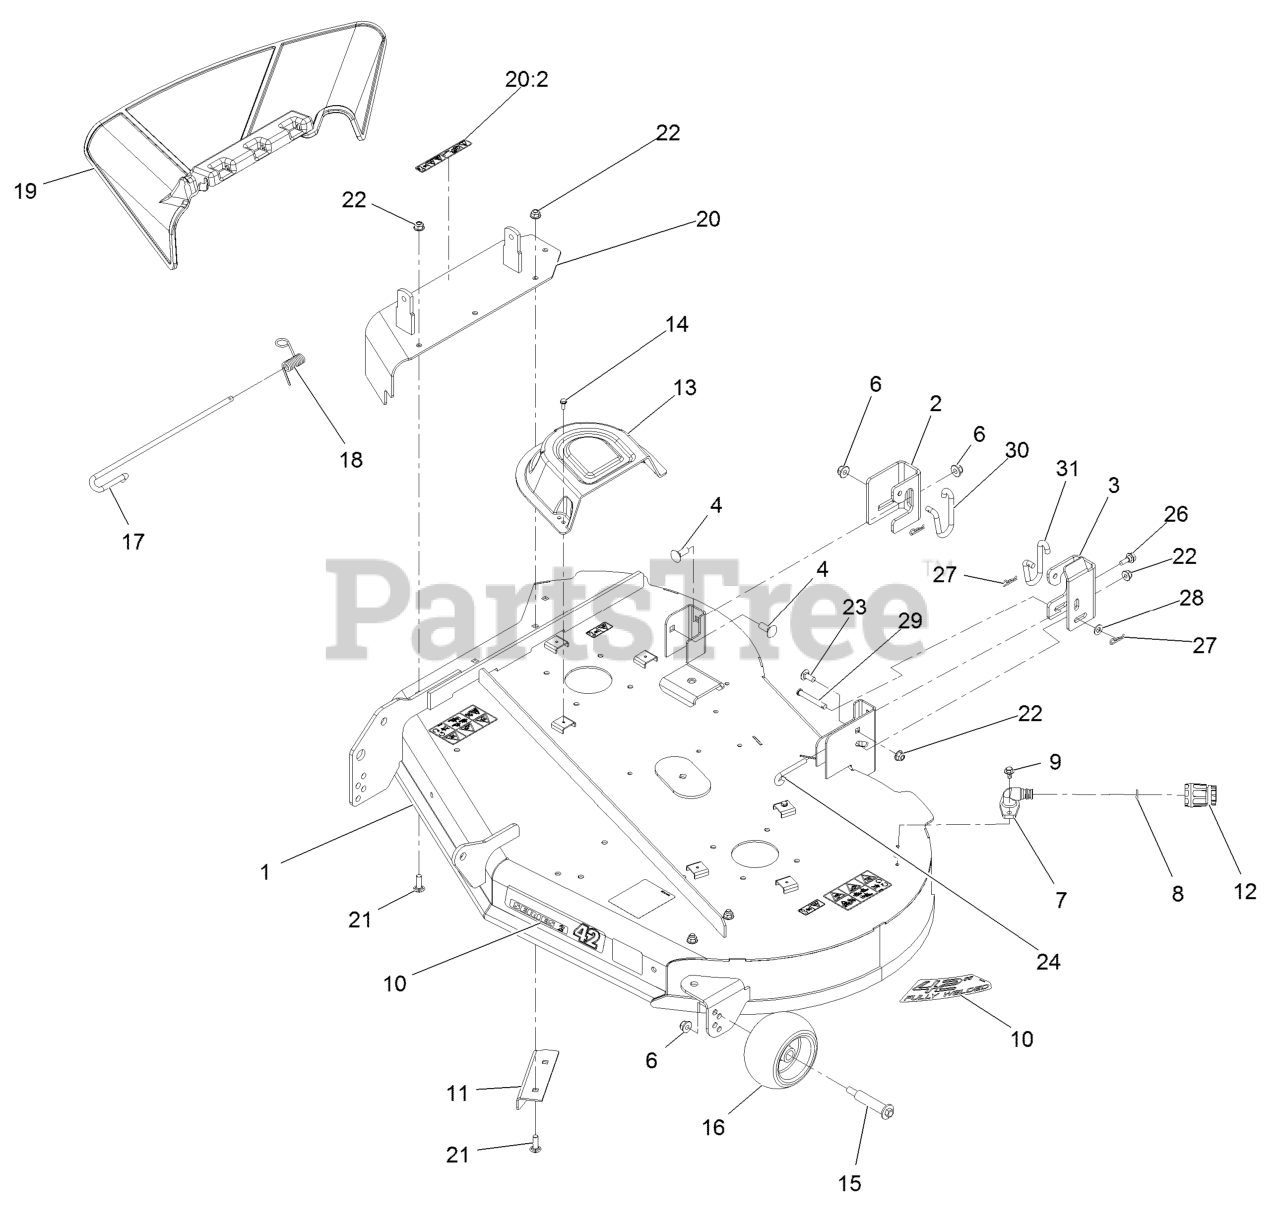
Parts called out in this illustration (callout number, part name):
1	42 INCH DECK ASM
2	BRACKET-HANGER, RH
3	BRACKET-HANGER, LH
4	BOLT-CARR
6	NUT-HF, NI
9	SCREW-HHFTF
10	Decal-Series 2 - 42
11	BAFFLE-CUTOFF
12	CONNECTOR-HOSE
13	COVER-BELT
14	SCREW-TAPTITE
15	BOLT-SHOULDER
16	ROLLER-SCALP, ANTI
17	PIN-CHUTE
18	SPRING-TORSION
19	DEFLECTOR-DISCHARGE
20	COVER ASM W/DECAL
20:2	DECAL-DANGER
21	SCREW-CARR
22	NUT-HF, NI
23	SCREW-CARR
24	ROD-LEVEL, DECK
26	SCREW-SHOULDER,HWH
27	PIN-COTTER
28	WASHER-PLAIN
29	PIN-CLEVIS
30	LINK-RETENTION, DECK (RH)
31	LINK-RETENTION, DECK (LH)
